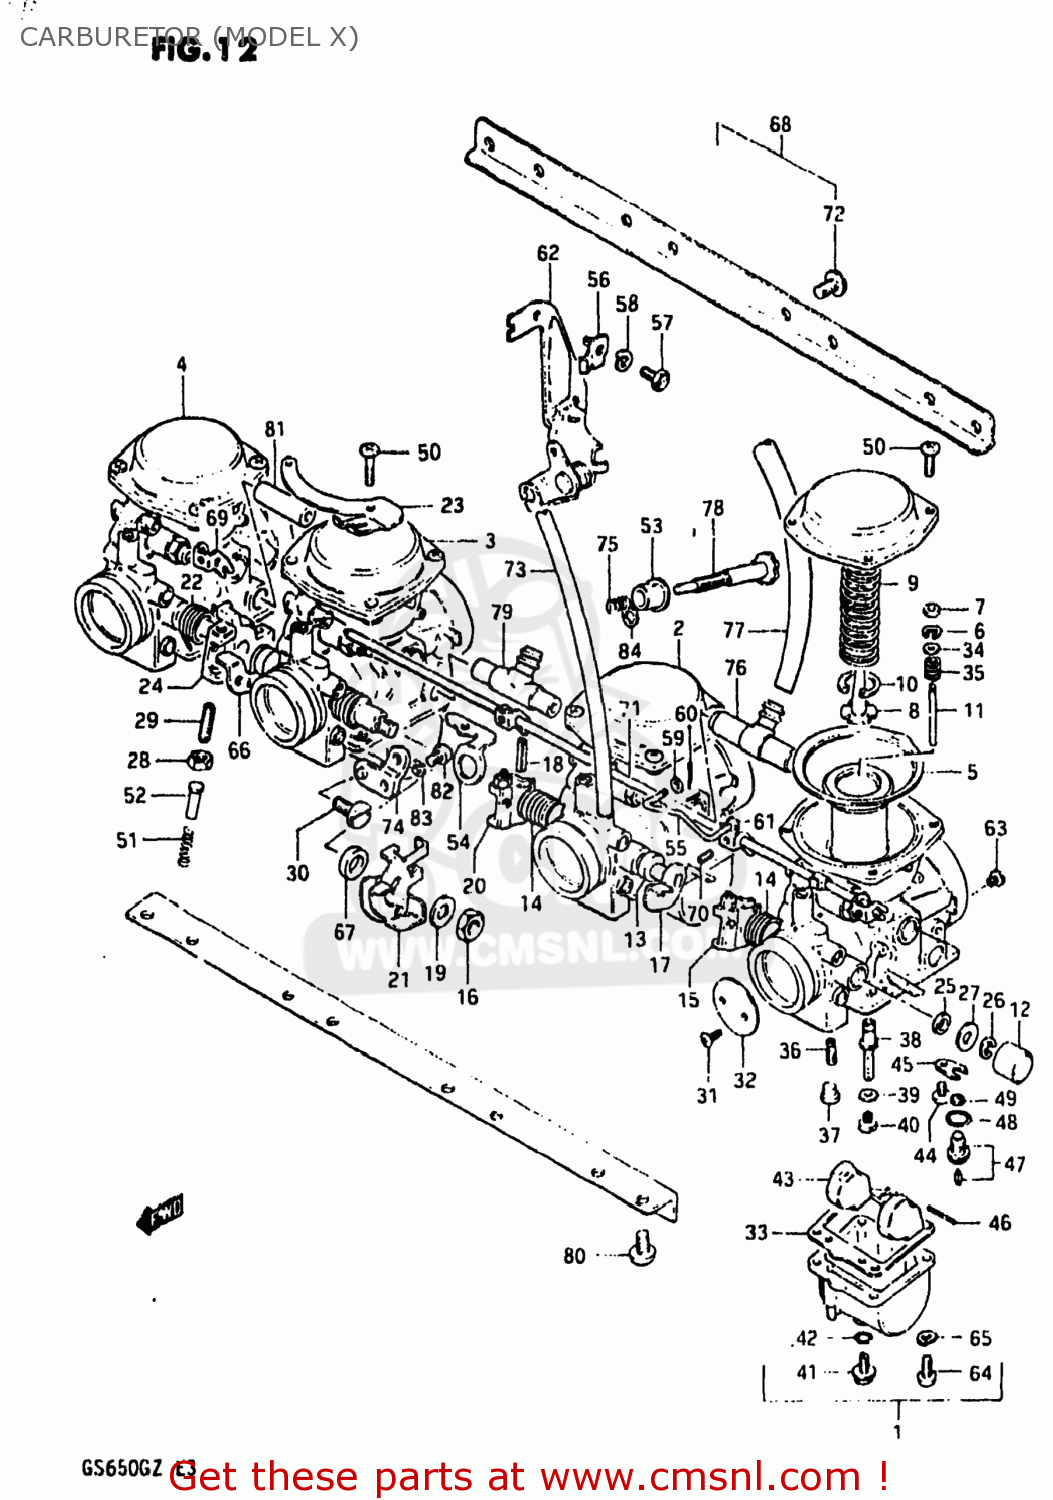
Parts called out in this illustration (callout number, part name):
1	CARBURETOR ASSEMBLY
2	CARBURETOR ASSEMBLY
3	CARBURETOR ASSEMBLY
4	CARBURETOR ASSEMBLY
5	DIAPHRAGM
6	CLIP,NEEDLE
7	RING
8	HOLDER,GUIDE
9	SPRING
10	E RING
11	NEEDLE JET
12	CAP
13	GASKET,THROTTLE SHAFT (NAS)
14	SPRING,THROTTLE SHAFT
15	SHAFT,THROTTLE
16	NUT 8MM
17	SHAFT,THROTTLE
18	PIN,THROTTLE SHAFT
19	WASHER
20	LEVER,THROTTLE SHAFT
21	LEVER ASSEMBLY,THROTTLE
22	SPRING,THROTTLE SHAFT
23	BRACKET
24	SHAFT,THROTTLE
25	SEAL
26	E RING
27	GASKET,THROTTLE SHAFT (NAS)
28	NUT
29	SCREW
30	SCREW
31	SCREW
32	VALVE,THROTTLE (BUTTERFLY)
33	GASKET,FLOAT CHAMBER (NAS)
34	WASHER
35	SPRING
36	JET,PILOT(42.5)
37	PLUG,NEEDLE JET
38	JET,NEEDLE
39	WASHER,NEEDLE NOZZLE
40	JET,MAIN(110)
41	PLUG,DRAIN
42	GASKET (NAS)
43	FLOAT
44	SCREW 4X6
45	PLATE,NEEDLE VALVE FITING
46	PIN,FLOAT
47	VALVE ASSEMBLY,NEEDLE
48	O-RING,NEEDLE VALVE
49	FILTER
50	SCREW
51	SPRING,THROTTLE SCREW
52	PIN,THROTTLE LEVER
53	BUSH
54	BRACKET,THROTTLE ADJUST
55	ROD,STARTER LEVER
56	BRACKET,STARTER
57	BOLT
58	LOCK WASHER
59	SEAT,SPRING
60	PIN
61	LEVER ASSY
62	BRACKET
63	JET
64	SCREW
65	LOCK WASHER
66	SHAFT,THROTTLE
67	WASHER
68	CARBURETOR ASSEMBLY
69	LEVER
70	SCREW
71	SHAFT,STARTER
72	SCREW
73	HOSE
74	BRACKET,THROTTLE ADJUST
75	SPRING
76	NIPPLE
77	HOSE
78	SCREW
79	NIPPLE,CARBURETOR
80	SCREW 6X12
81	NIPPLE
82	SCREW
83	LOCK WASHER
84	WASHER
